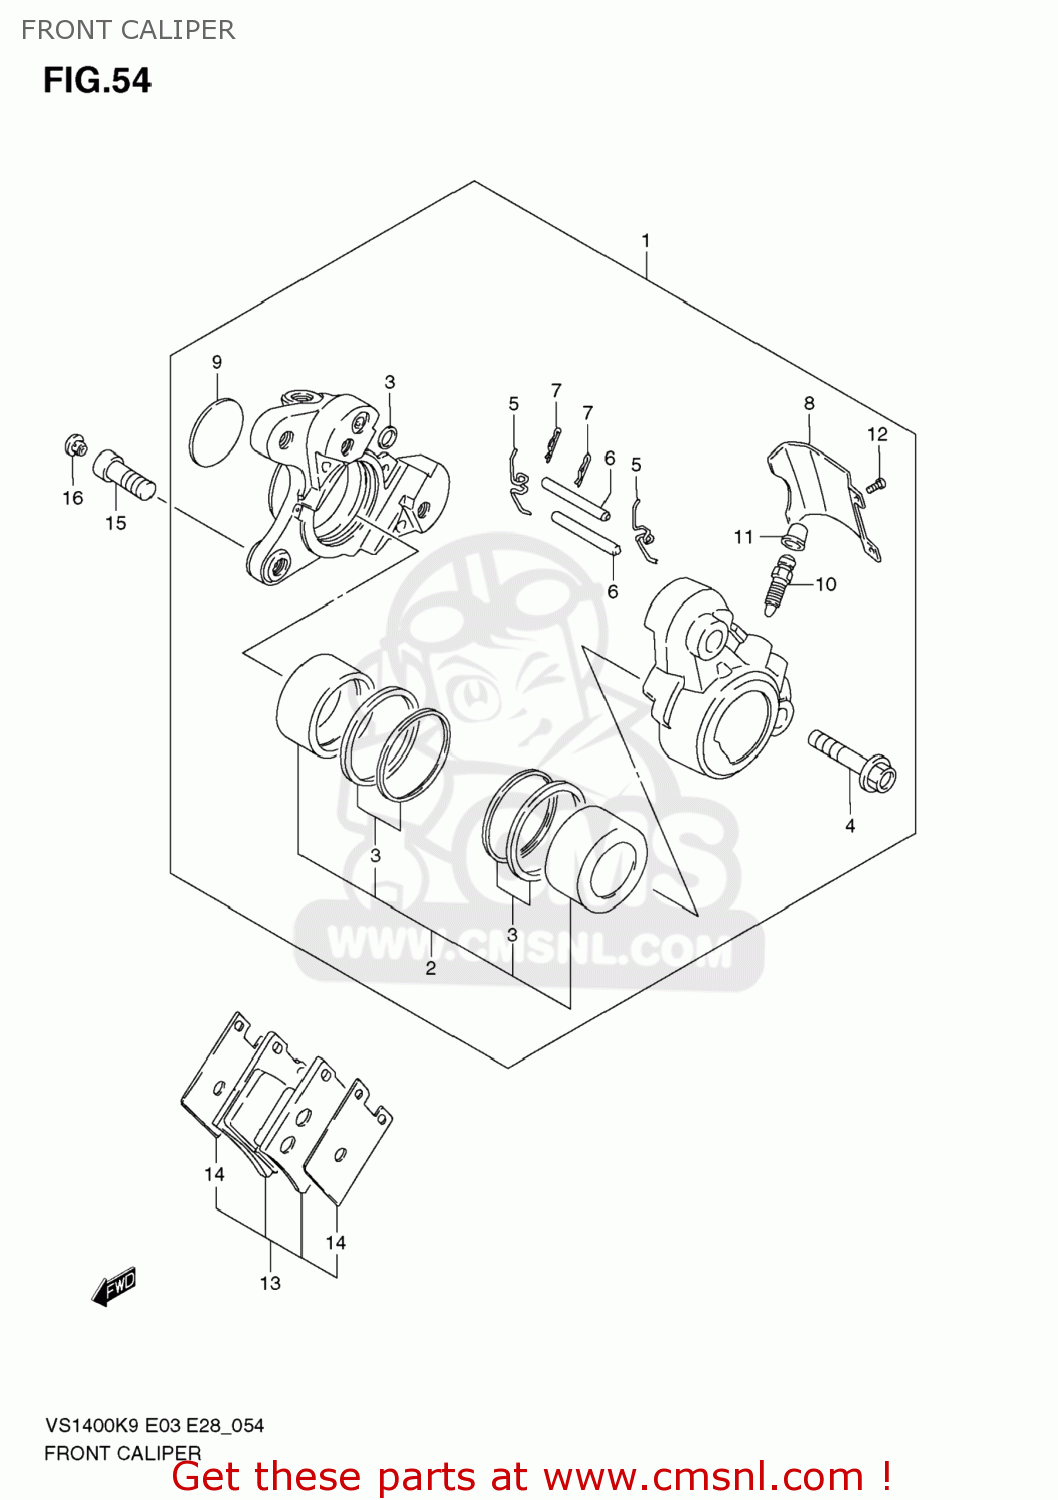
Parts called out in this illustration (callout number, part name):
1	CALIPER ASSY,FR,R
2	PISTON SET
3	SEAL SET,PISTON
4	BOLT,HOUSING
5	SPRING
6	PIN,PAD
7	CLIP,PAD PIN
8	COVER,CALIPER HOUSING,DUST
9	CAP,CALIPER
10	BLEEDER
11	CAP,BLEEDER PLUG
12	SCREW,CALIPER COVER(4X6)
13	PAD & SHIM SET (NAS)
14	SHIM,PAD
15	BOLT(10X33)
16	CAP(OD:12)
